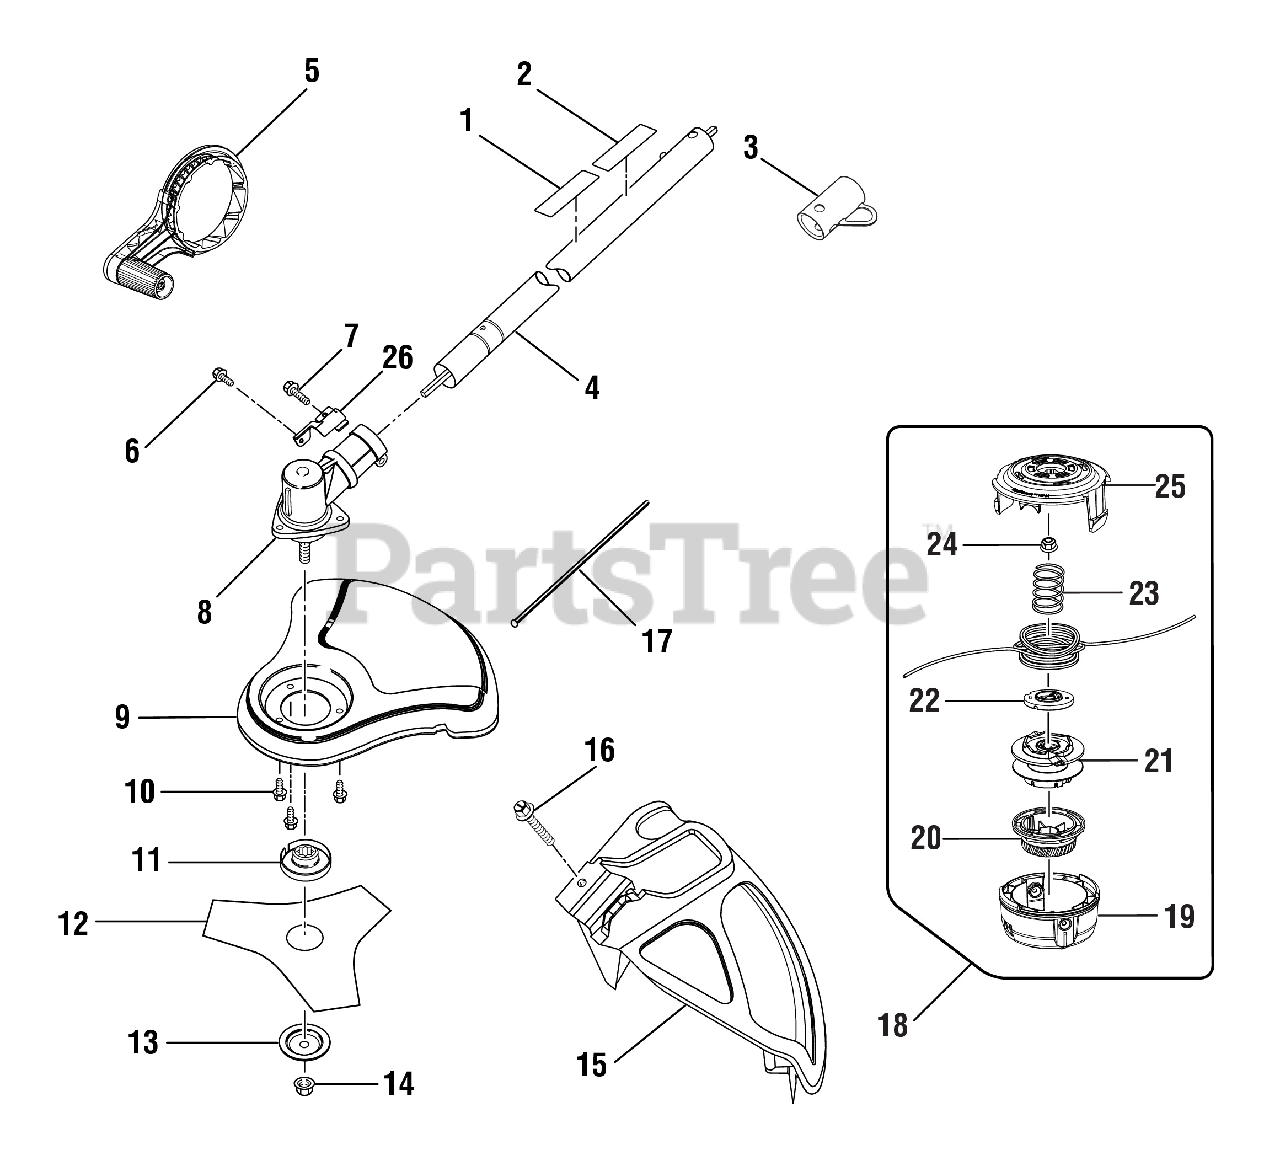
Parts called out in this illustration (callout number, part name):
1	Ryobi EXPAND-IT Label
2	Brushcutter Safety Label
3	Storage Hanger Cap
4	Lower Straight Shaft Boom Assembly
5	Crank Handle Assembly
6	Screw (1/4-20 x 1-1/4 in., Hex Washer Hd. S.T.)
7	Screw w/Washer (10-24 x 5/8 in., Hex Hd. T.F.)
8	Gear Case Assembly
9	8 in. Blade Guard
10	Screw w/Washer (10-24 x 1/2 in., Slotted Hex Hd.)
11	FLANGED WASHER
12	BLADE (TRI-ARC(TM))
13	CUPPED WASHER
14	Lock Nut (M8 x 1.25 in., Left Hand Threads)
15	Grass Deflector Assembly
16	SCREW (#1/4-20 X 1-1/4 in. HEX WASHER HD.)
17	Gear Head Locking Tool
18	Trimmer Head Assembly (.095)
19	Lower Housing
20	Bump Knob (Green)
21	Spool Assembly
22	String Guide
23	Compression Spring
24	Hex Nut (M8, Left Hand Threads)
25	Upper Housing
26	Grass Deflector Clamp
